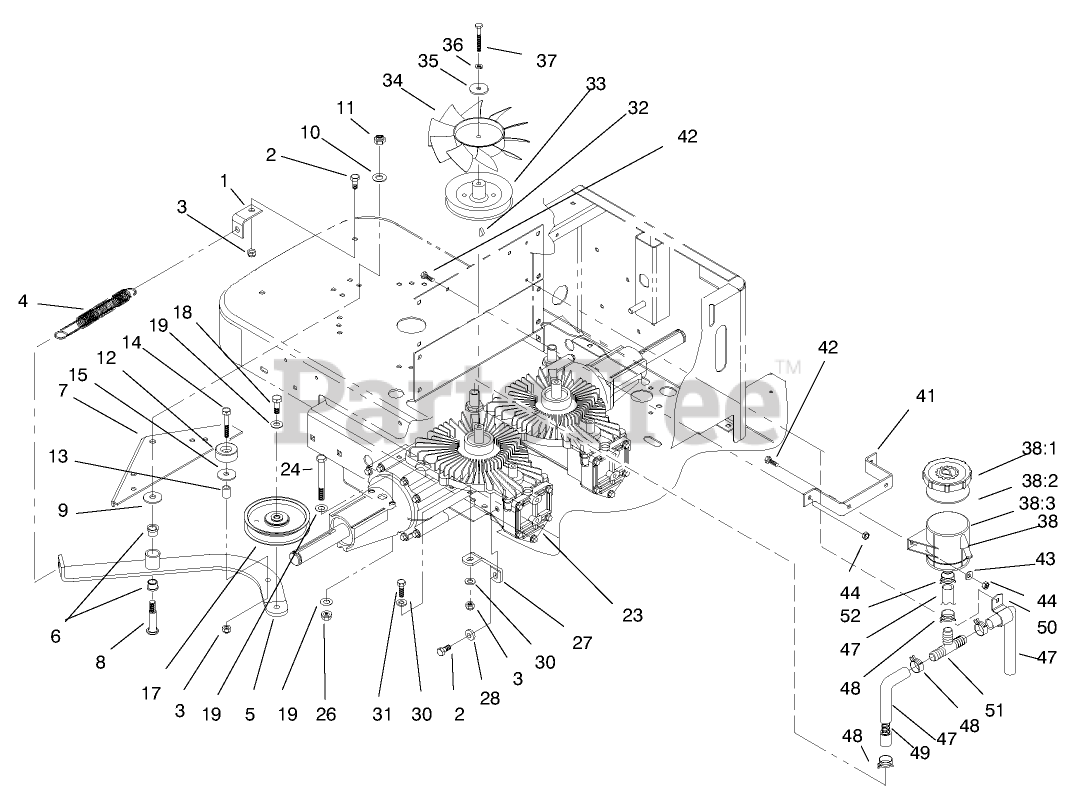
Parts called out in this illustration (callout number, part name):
1	BRACKET-SPRING
2	SCREW-HH
3	NUT-LOCK, NI
4	SPRING-EXTENSION
5	Idler-Arm
6	BUSHING
7	STIFFENER
8	BOLT-SHOULDER
9	WASHER
10	WASHER-FLAT
11	NUT-HEX
12	BUMPER
13	SPACER
14	SCREW-HH
15	WASHER
17	PULLEY IDLER
18	SCREW-HH
19	WASHER-FLAT
22	V-BELT
23	TRANSAXLE-781
24	SCREW-HH
26	NUT-LOCK, NI
27	Bracket
28	Washer-Special
30	WASHER-PLAIN
31	SCREW-HH
32	KEY WOODRUFF
33	PULLEY
34	FAN-7"
35	WASHER
36	WASHER-LOCK
37	SCREW-HH
38	ASS'Y-RESERVOIR
38:1	COVER GASKET
38:2	COVER
38:3	RESERVOIR
41	BRACKET
42	SCREW-HH
43	WASHER-FLAT
44	NUT-LOCK, NI
47	HOSE-7"
48	CLAMP .875
49	COMPRESSION SPRING
50	CLAMP
51	TEE-5/8 PLASTIC
52	CLAMP-HOSE
